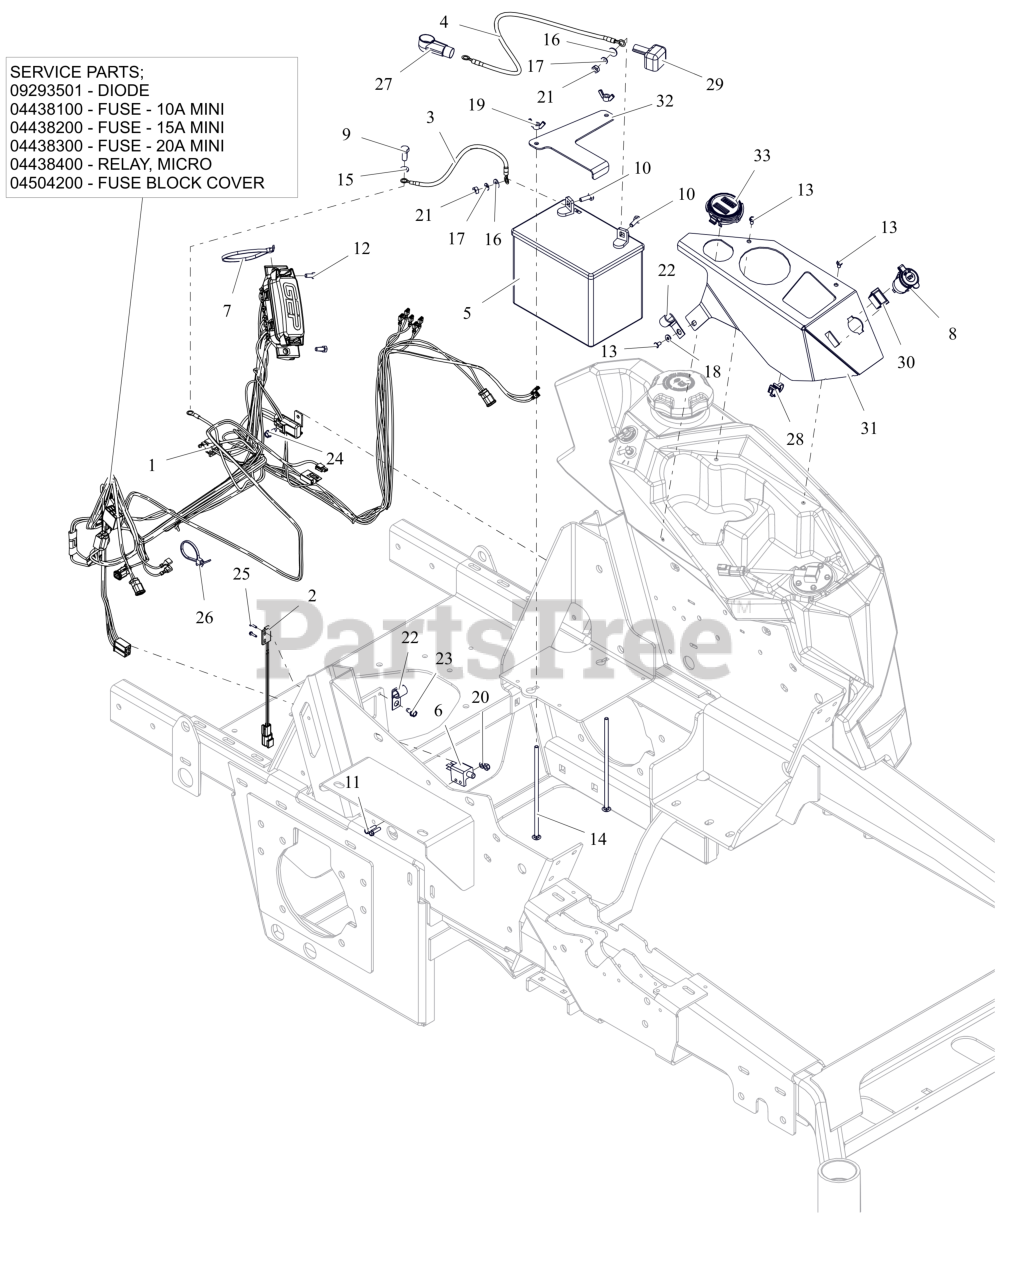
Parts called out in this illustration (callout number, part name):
1	HARNESS, ELECTRICAL 421
1	DIODE, CONNECTOR SHELL
1	FUSE,10 AMP MINI-ATC
1	FUSE,15 AMP MINI-ATC
1	FUSE,20 AMP MINI ATC
1	RELAY,MICRO5 TERML W/RESISTOR
1	COVER, HARNESS FUSE/RELAY MOD
2	SWITCH, MAGNETIC
3	CABLE, NEGATIVE BATTERY 11.5 LNG
4	CABLE, POS W/(2) .312 RING 16.0 LG
5	BATTERY, 300 CCA 10U1L
6	SWITCH- DOUBLE POLE N.O./N.O.
7	TIE WRAP
8	PORT, 12 VOLT POWER
9	BLT, HEX M8-1.25X20 G8.8 ZCC
10	BLT, HEX .25-20X.75 G5 ZCC
11	BLT, HWH #10-24X.75 ZCC
12	BLT, HEX M6-1X16 G8.8 ZCC
13	SCR-MCH 10-24X.38 HWHSTAINLESS
14	BTL,RHSN .250-20 X 7.5 G5 ZCC
15	WSHR,LK-REG .312X.078 ZCC
16	WSHR,FLT .281X.625X.065 ZCC
17	WSHR,LK-REG .250X.062 ZCC
18	WSHR-FL-STL .196X.50X.06 ZC120
19	NUT, LK-WING .25-20 ZCC
20	NUT-LK-NYL #10-24 G2 ZCC
21	NUT-STD .250-20 G2 ZCC
23	SCR-TAP .25-20X.50 HWH ZCC
24	SCR,TAP .25-20X.625 HWH ZCC
25	SCR-TAP #4-40X.50 HWH ZCC
26	CABLE TIE W/ TREE (.25 HOLE)
27	BOOT, .65ID POS
28	TIE, EC23 MOUNT W CABLE
29	INSULATOR
30	SWITCH,BLANK
31	PANEL, LH CONTROL (RED)
32	HOLDDOWN, BATTERY (BLACK)
33	DUAL METER
